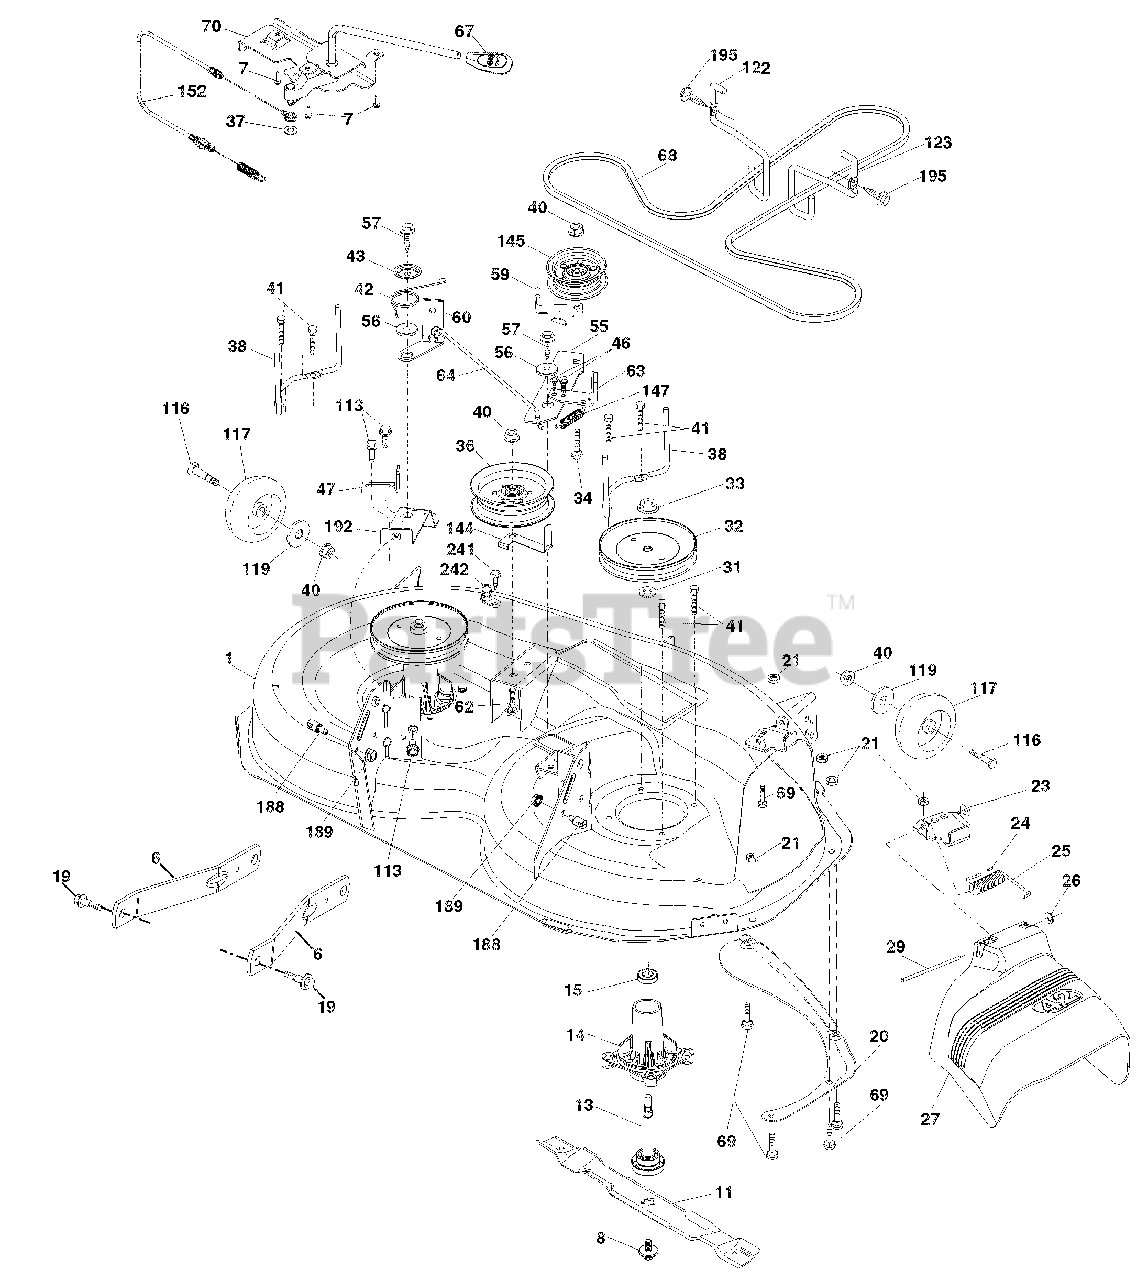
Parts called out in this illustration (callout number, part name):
1	DECK.PNT.WELDMENT.42"
6	ARM.SUSPENSION.MOWER.REAR.LD
8	BOLT/WASHER ASM.7/16-20.UNF
11	BLADE.MOWER.42"HI LIFT PREMIUM
13	SHAFT ASM.MNDRL.N/GREASEABLE38
14	HOUSING.MANDREL.4PT.SERVICE
15	BEARING.BALL.MANDREL
19	BOLT.SHOULDER
20	BAFFLE.VORTEX.42.STD/HEAVY DTY
21	Nut, Hex, Crownlock 5/16-18
23	BRACKET.DEFLECTOR.38/42"2005
24	CAP.SLEEVE..80X.112.BLK.MOWER
25	SPRING.TORSION.DFL.38/42/46.GR
26	NUT.PUSH.PHOS.& OIL
27	SHIELD.DEFLECTOR.
29	ROD.HINGE.42/46"
31	WASHER.SPACER.MANDREL
32	PULLEY.MANDREL.5.438 PD.42"
33	NUT.FLANGE.LOCK.TOP
34	BOLT.CARR.SH.3/8-16X1-1/2.GR5
36	PULLEY.IDLER.4.50.RAW
37	WASHER.13/32 X 13/16 X 16 GA.
38	KEEPER.BELT.MANDREL.PULLEY
40	Nut, Hex, Flangelock 3/8-16
41	HEX HEAD BOLT
42	SPRING.TORSION.BRAKE
43	SPRING.TORSION.RETAINER
46	SCREW.THD.ROLL.1/4-20 X 5/8
47	BRACKET.CLUTCH.CABLE
55	IDLER.ARM
56	SPACER.RETAINER
57	SCREW.3/8-16X1.SMGML.TAP/R.BLK
59	GUARD.TUV.IDLER
60	ARM.BRAKE.MOWER.42"
62	BOLT.RD.HD.SQ.NK.3/8-16UNC X 2
63	ARM.BRAKE.MOWER
64	LINKAGE.BRAKE
67	HANDLE.CLUTCH.CABLE.LT TEX.428
68	BELT.DRIVE.100.97"
69	BOLT.RDHD.SQNK.5/16-18 X 5/8
70	CLUTCH ASM.
113	BOLT.5/16-18HEX.WHS.HD.LCKSERR
116	BOLD SHLD "A" 2.41 "B" 1.66
117	WHEEL.GAGE.HALF.SPOKED
119	Washer 3/8 x 7/8 x 14 Ga.
122	KEEPER.BELT.ENGINE.LH.LT.TEX
123	KEEPER.BELT.ENGINE.RH.LT.TEX
144	KEEPER.BELT.MOWER
145	PULLEY.IDLER 48"PRIMARY
147	SPRING.RETURN
152	CABLE.CLUTCH.MANUAL
188	STUD.FASTNER.W/'D'ANTI-ROTATIO
189	Nut, Lock Hex Flange 5/16-18 u
192	BRACKET.BRAKE.STAND.LH
195	SCREW.5/16-18X3/4.SMGML.TAP/BL
242	PORT WASHOUT
